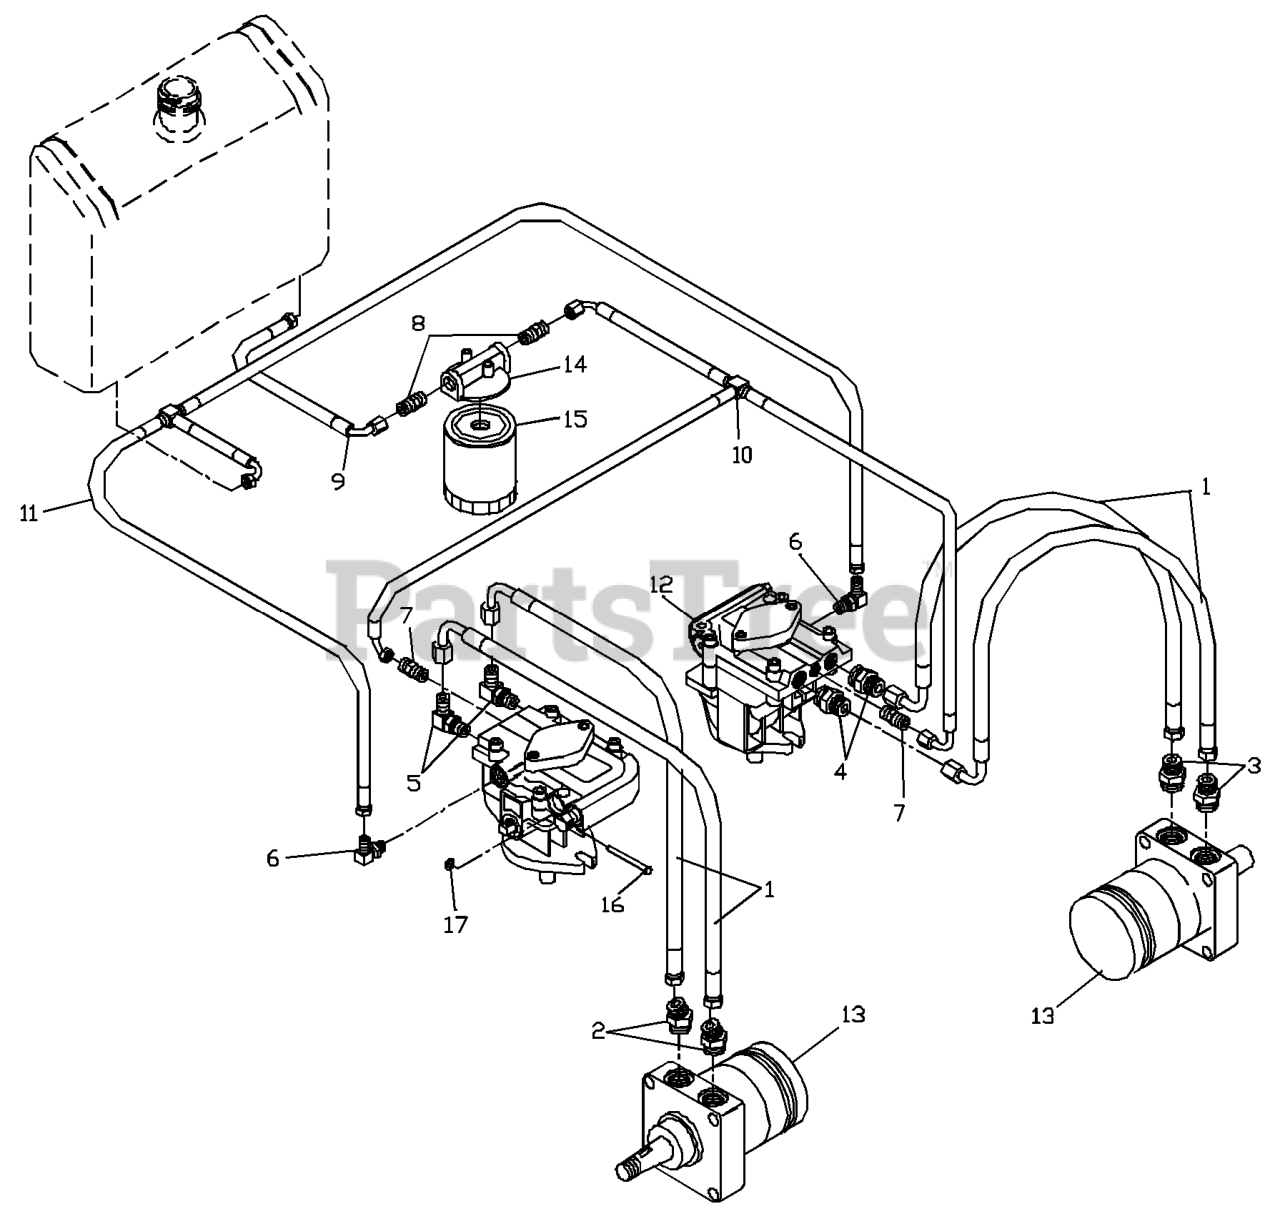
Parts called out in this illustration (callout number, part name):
1	HOSE, 1/2" HYDRAULIC
2	ELBOW-ADJ 45 DEG F6802-8-10
3	CONNECTOR, STRAIGHT
4	FITTING, STRAIGHT F6400-8-8-0
5	ELBOW, 90 DEGREE
6	ELBOW, F6801-6-6-0 90 DEGREE
7	FITTING, STRAIGHT F6400-6-4-0
8	STRAIGHT FITG
9	HOSE
10	INLET TEE HOSE
11	RETURN TEE HOSE
13	WHEEL MOTOR
14	FILTER HEAD
15	HYDRAULIC OIL FILTER
16	CLEVIS PIN
17	NUT PUSH
